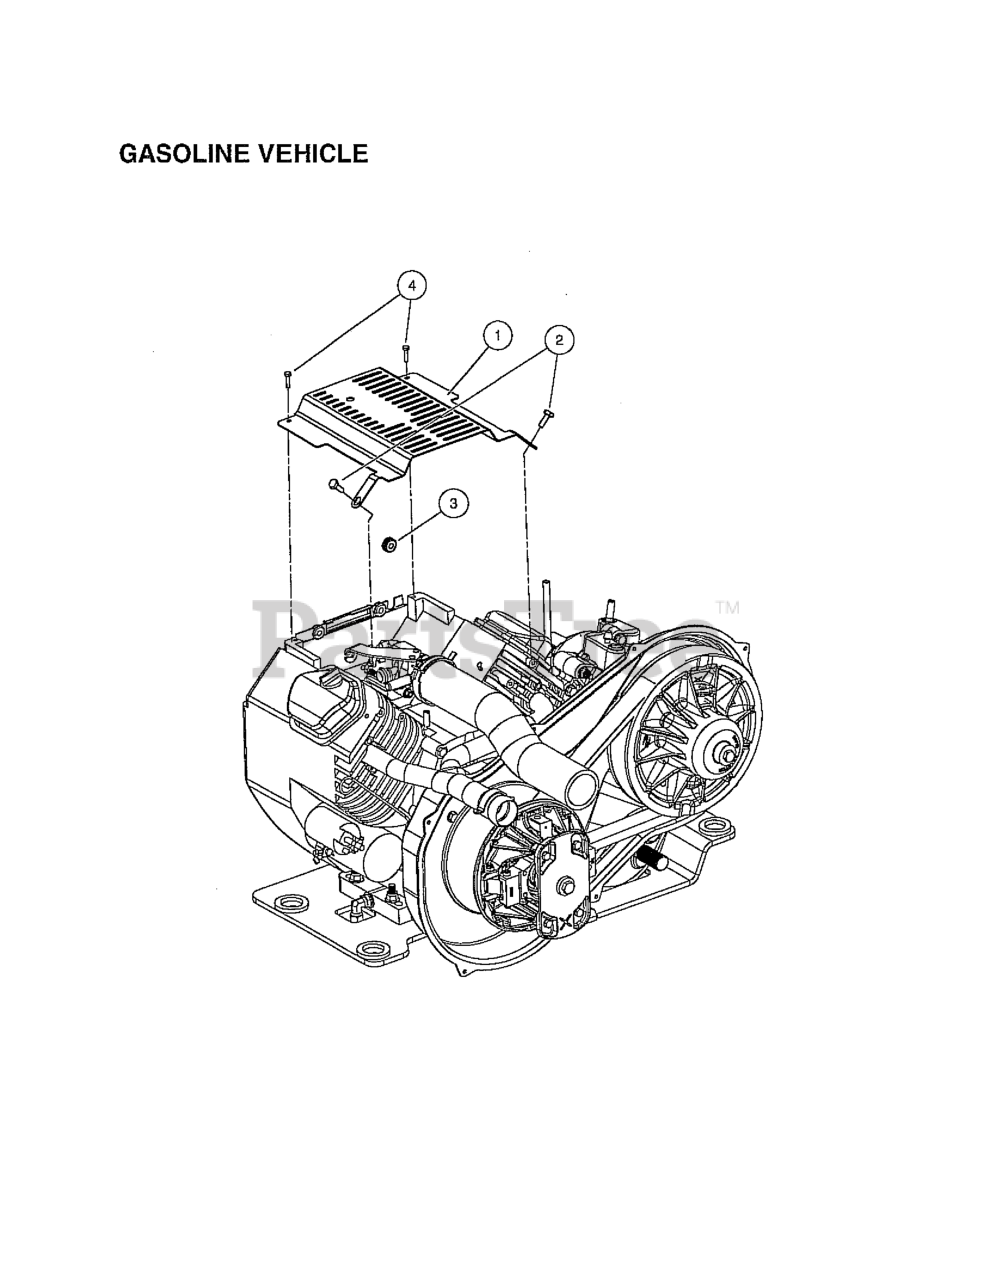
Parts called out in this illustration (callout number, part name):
1	COVER, ENGINE, HONDA
2	BOLT, M8 X 1.25 X 20
3	GROMMET, SPLIT, 50 DUROMETER
4	BOLT, M5 X .8 X 20
